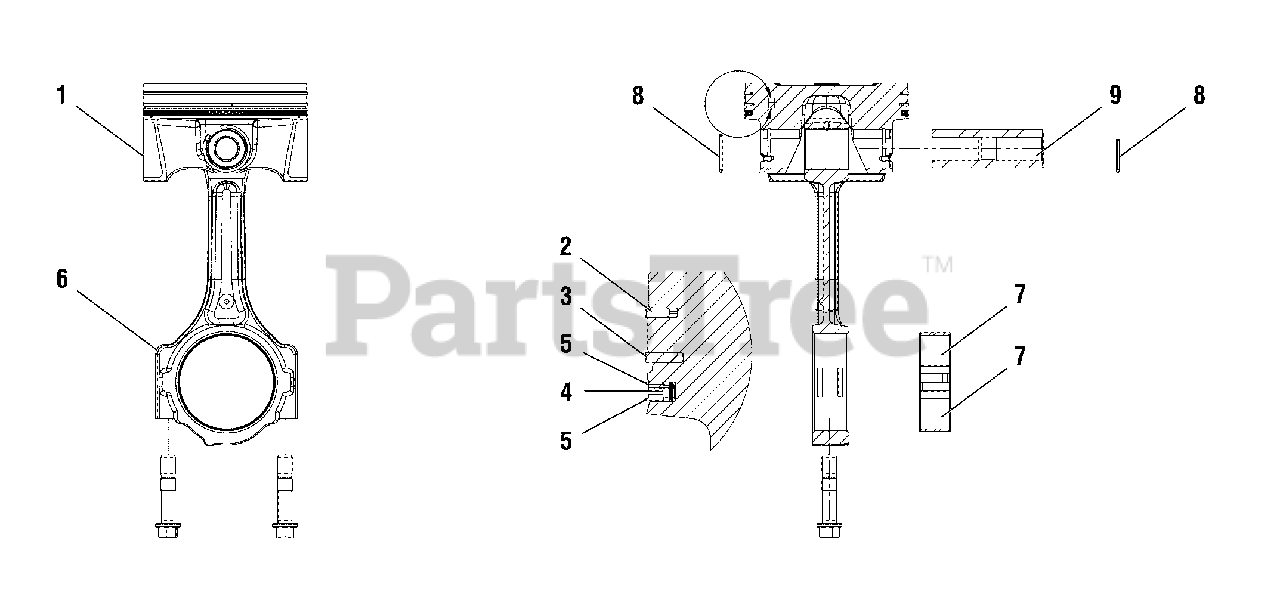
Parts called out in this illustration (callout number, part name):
1	PISTON
2	SET, PISTON RING
3	SET, PISTON RING
4	SET, PISTON RING
5	SET, PISTON RING
6	ROD, CONNECTING
7	BEARING, C/ROD
8	CLIP, PISTON
9	PIN, PISTON
